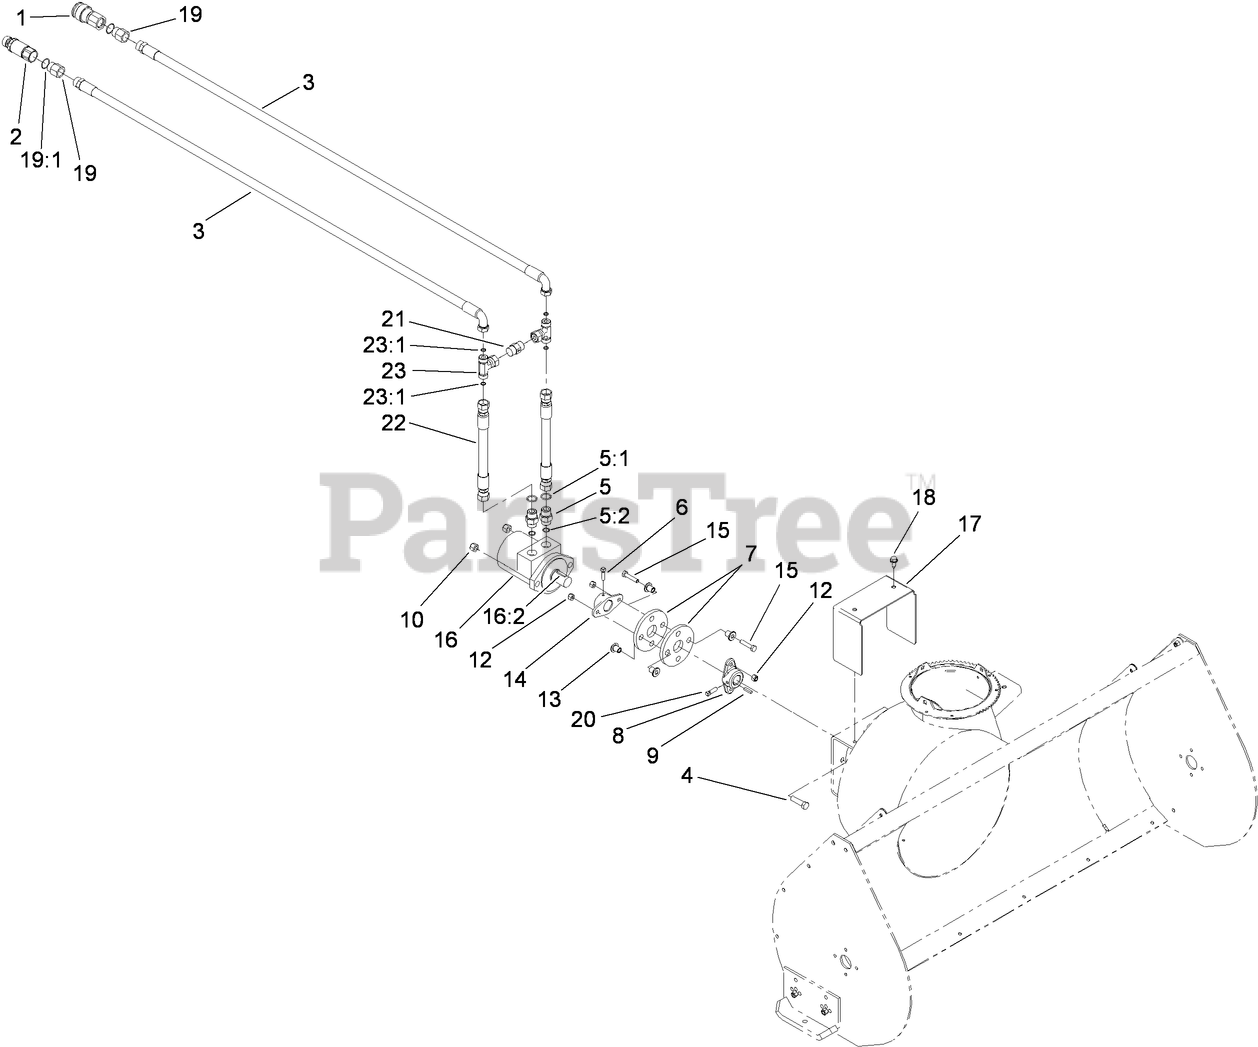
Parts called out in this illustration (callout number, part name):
1	COUPLER-FACE, FLUSH
2	NIPPLE-CONNECT, PRESSURE
3	HOSE-HYD
4	SCREW-HH
5	FITTING-STRAIGHT
5:1	O-RING
5:2	O-RING
6	SCREW-SET
7	COUPLING-RUBBER
8	HUB-PUMP
9	KEY
10	NUT-LOCK, NI
12	NUT-LOCK, NI
13	SPACER
14	HUB-ENGINE
15	SCREW-HH
16	HYD MOTOR ASM
16:2	KEY-SQUARE
17	SHIELD-MOTOR
18	SCREW-HWHTF
19	ADAPTER-HYD
19:1	O-RING
20	SCREW-SET, SQH
21	VALVE-CHECK
22	HYD HOSE ASM
23	FITTING-TEE
23:1	O-RING
